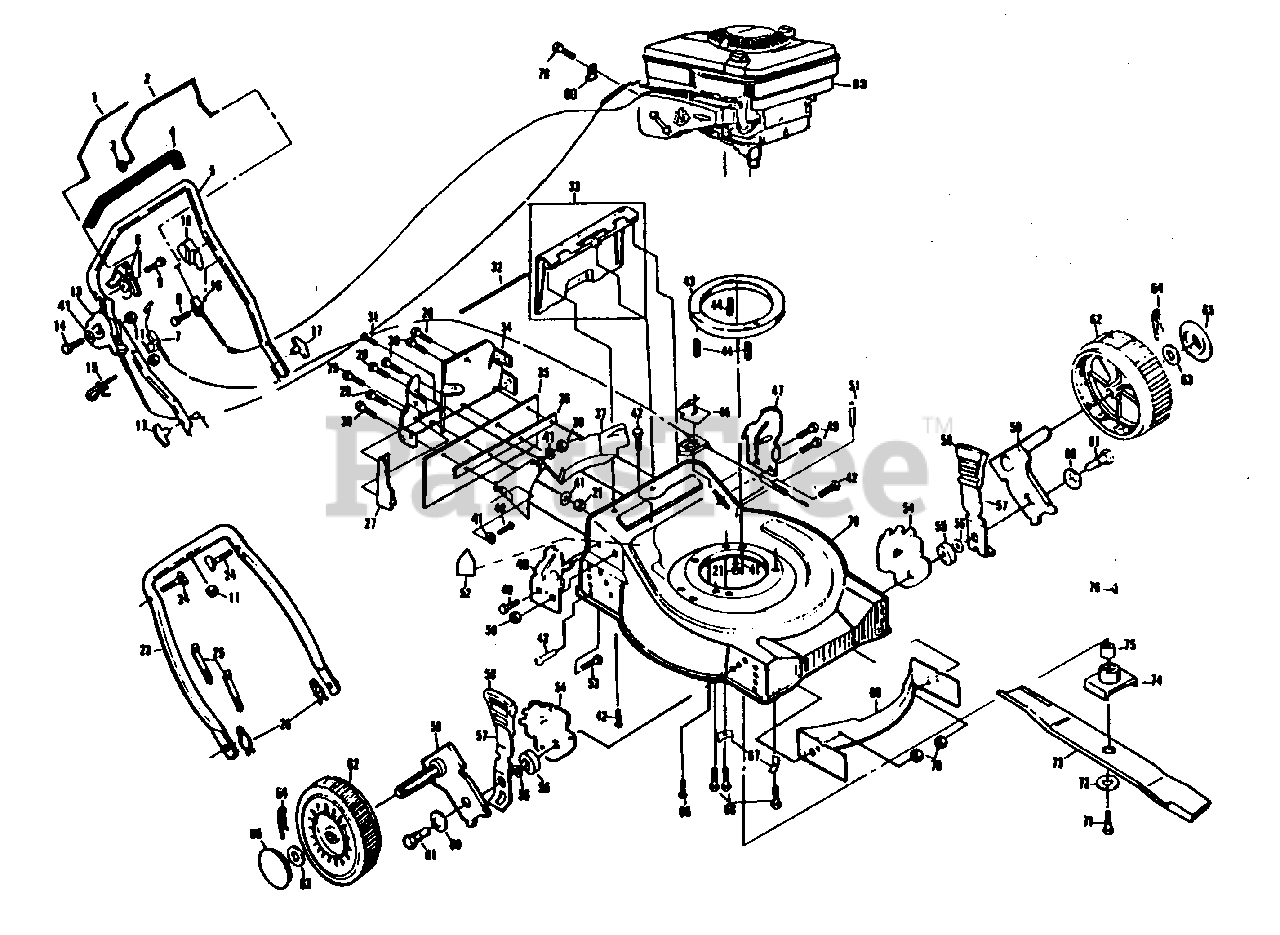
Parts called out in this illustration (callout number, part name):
1	Drive Bar
2	Engine Control Bar
3	Flat Washer (AYP part number)
4	Handle Grip (AYP part number)
5	Upper Handle (AYP part number)
6	Drive Control Actuator (AYP part number)
7	Drive Cable Assembly (AYP part number)
8	Thread Rolling Screw #10-24 x 3/4 (AYP part number)
9	Self-tapping Screw #10-24 x 5/8 (AYP part number)
10	Zone Control Actuator (AYP part number)
11	Locknut 1/4-20 (AYP part number)
13	Throttle Control
14	Machine Screw 1/4-20 x 2-1/8 (AYP part number)
15	Rope Guide (AYP part number)
16	Engine Zone Control Cable
17	Handle Knob (AYP part number)
21	Locknut 1/4-20 (AYP part number)
23	Lower Handle (AYP part number)
24	Handle Bolt 5/16-18 x 1-3/4
25	Wire Ties (AYP part number)
26	Hairpin Cotter (AYP part number)
27	Side Baffle (AYP part number)
28	Pop Rivet (AYP part number)
29	Hex Head Screw 1/4-20 x 3/4 (AYP part number)
30	Hex Tapping Screw 1/4-20 x 1/2 (AYP part number)
31	Hex Washer Head Machine Screw #10-24 x 9/16 (AYP part number)
32	Hinge Rod (AYP part number)
33	Rear Door Kit (AYP part number)
34	Back Plate (AYP part number)
35	Rear Skirt (AYP part number)
36	Backing Strip (AYP part number)
37	Rear Baffle
38	Locknut (AYP part number)
40	Hex Washer Head Tapping Screw #10-24 x 1/2 (AYP part number)
41	Washer (AYP part number)
42	Hex Tapping Screw 1/4-20 x 1/2 (AYP part number)
43	Engine Spacer (AYP part number)
44	Engine Bushing (AYP part number)
46	Bracket Cover (AYP part number)
47	Handle Bracket Assembly (Left) (AYP part number)
48	Handle Bracket Assembly (Right) (AYP part number)
49	Thread Cutting Screw 5/16-18 x 3/4 (AYP part number)
50	Locknut 5/16-18 (AYP part number)
51	Carriage Bolt 1/4-20 x 1/2 (AYP part number)
52	Danger Decal (AYP part number)
53	Carriage Bolt 5/16-18 x 5/8 (AYP part number)
54	Wheel Adjusting Bracket (AYP part number)
55	Spacer (AYP part number)
56	Washer (AYP part number)
57	Selector Spring (AYP part number)
58	Selector Knob (AYP part number)
59	Axle Arm Assembly (AYP part number)
60	Belleville Washer (AYP part number)
61	Shoulder Bolt 3/8-16 (AYP part number)
62	Wheel & Tire Assembly 8.0 x 1.75 (AYP part number)
63	Washer (AYP part number)
64	Retainer Clip (AYP part number)
65	Hubcap (AYP part number)
66	Self Tap Screw #10-24 x .75 (AYP part number)
67	Engine Washer (AYP part number)
68	Hex Head Thread Rolling Screw 3/8-16 x 2 (AYP part number)
69	Front Baffle (AYP part number)
70	Locknut 3/8-16 (AYP part number)
71	Hex Head Machine Screw Gr. 8 (AYP part number)
72	Helical Washer 3/8 (AYP part number)
73	22" Blade (AYP part number)
74	Blade Adapter (AYP part number)
75	Spacer (AYP part number)
76	Hi-Pro Key #HP-505 (AYP part number)
78	Lawn Mower Housing (Inc. 52)
79	Thread Rolling Screw #10-32 x 5/8 (AYP part number)
80	Cable Clamp (AYP part number)
